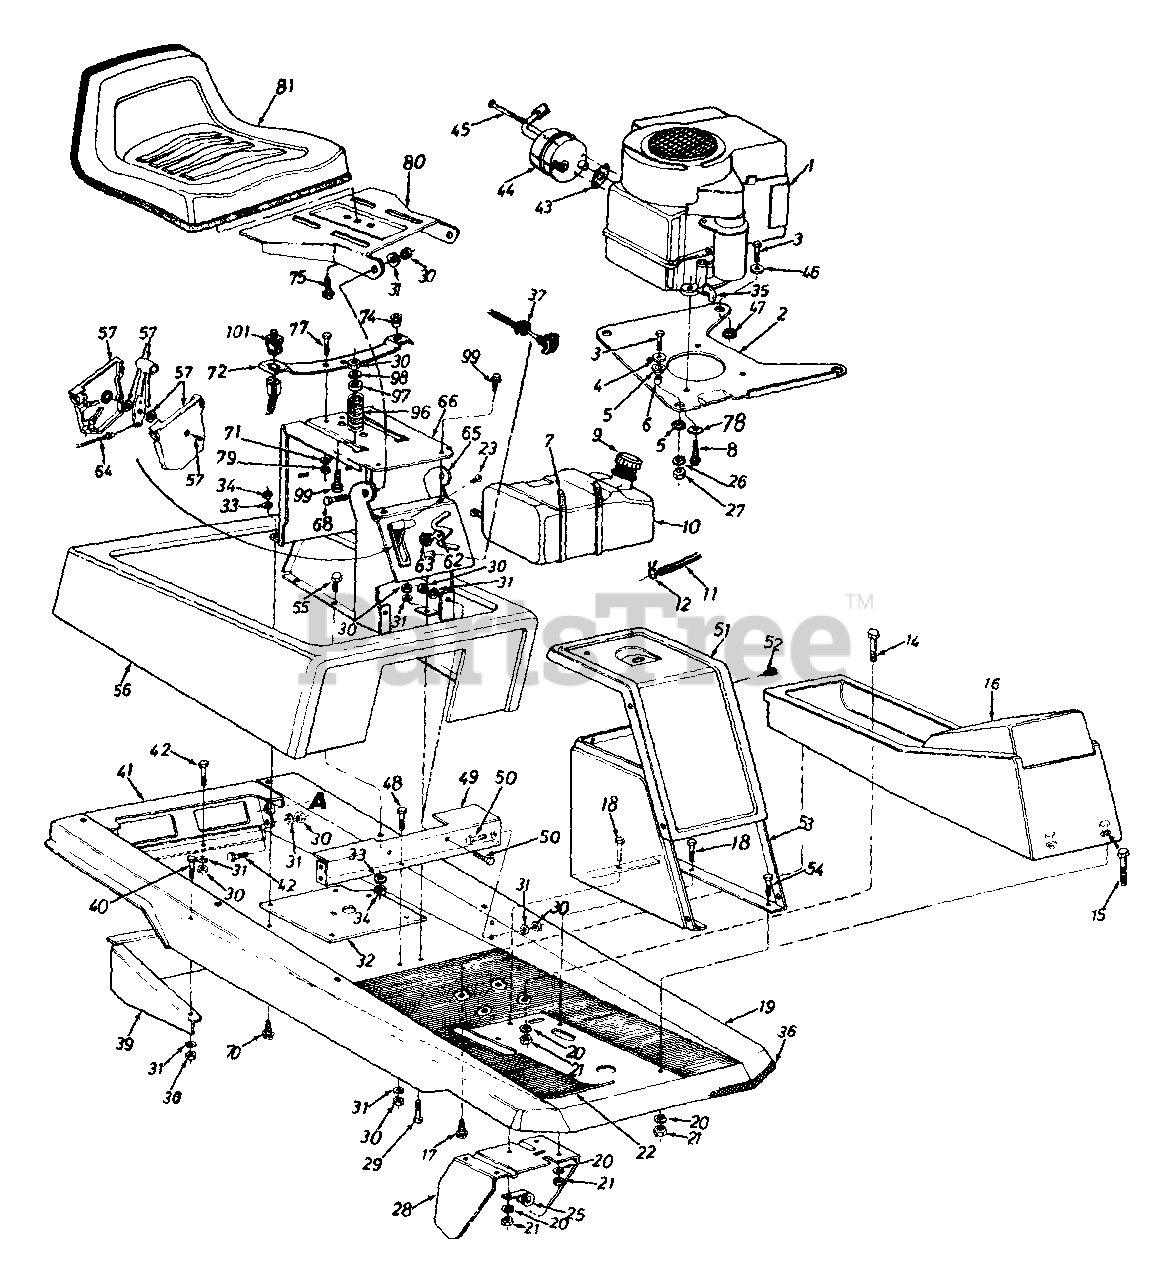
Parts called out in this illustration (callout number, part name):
1	Engine
4	Fl-Wash. .330" I.D. x 1.125" O.D.
5	Engine Mounting Grommet
6	Spacer .315" I.D. x .50" O.D. x .520" Lg.
7	Cable Tie 30.6 Lg.
8	Hex Wash. Hd. Self-Tap Scr. 3/8-16 x 1.25" Lg.
9	Gas Cap
10	Fuel Tank
11	Fuel Line - 26" Lg.
12	Hose Clamp - 1/2" O.D. Tube
14	Hex Bolt 5/16-18 x 1.75" Lg.
15	Hex Bolt 5/16-18 x 2" Lg."
16	Front Console
17	Plastite Scr. 5/16 x 1.25" Lg.
18	Hex Bolt 5/16-18 x .75" Lg.
19	Main Frame
20	L-Wash. 5/16" I.D.
21	Hex Nut 5/16-18 Thd.
22	Floor Mat
23	Truss Mach. AB-Tap Scr. #10 x .50" Lg.
25	Clamp
26	L-Wash. 5/16" I.D.
27	Hex Nut 5/16-24 Thd.
28	Clutch-Brake Pedal Ass'y.
29	Hex Bolt 5/16-18 x .75" Lg
30	Hex Nut 5/16-18 Thd.
31	L-Wash. 5/16" I.D.
34	Hex Nut 1/4-20 Thd.
35	90ø Elbow Male To Female
36	Trim Strip
37	Choke Control
43	Exhaust Gasket (8 H.P. B&S)
44	Muffler Ass'y. (8 H.P. B&S)
45	Shld. Bolt (8 H.P. B&S)
46	Fl-Wash. .330" I.D. x 1.25" O.D.
47	Flange Wash. .320" I.D. x .750" O.D.
49	Seat Support & Frame Brkt.
50	Hex Bolt 5/16-18 x .75" Lg.
55	Hex Bolt 1/4-20 x .50" Lg.
62	Ignition Key
63	Ignition Switch
64	Throttle Control Wire 35" Lg.
70	Hex Tap Scr. 1/4-20 x 1.0" Lg.
71	L-Wash. 5/16" I.D.
72	Seat Spring
74	Grommet
75	Hex Wash. Hd. Tap Scr. 3/8-16 x 3/4" Lg.
77	Hex Bolt 5/16-18 x .75" Lg.
78	Bell-Wash. .345" I.D. x .88" O.D.
79	Hex Cent. L-Nut 5/16-18 Thd.
80	Seat Pivot Bracket
81	Seat Ass'y. Comp.
96	Compression Spring 2.7" Lg.
97	Bushing
98	Fl-Wash. .344" I.D. x .875"
99	Hex Bolt 5/16-18 x 1" Lg. (Gr. 5)
101	Seat Switch
